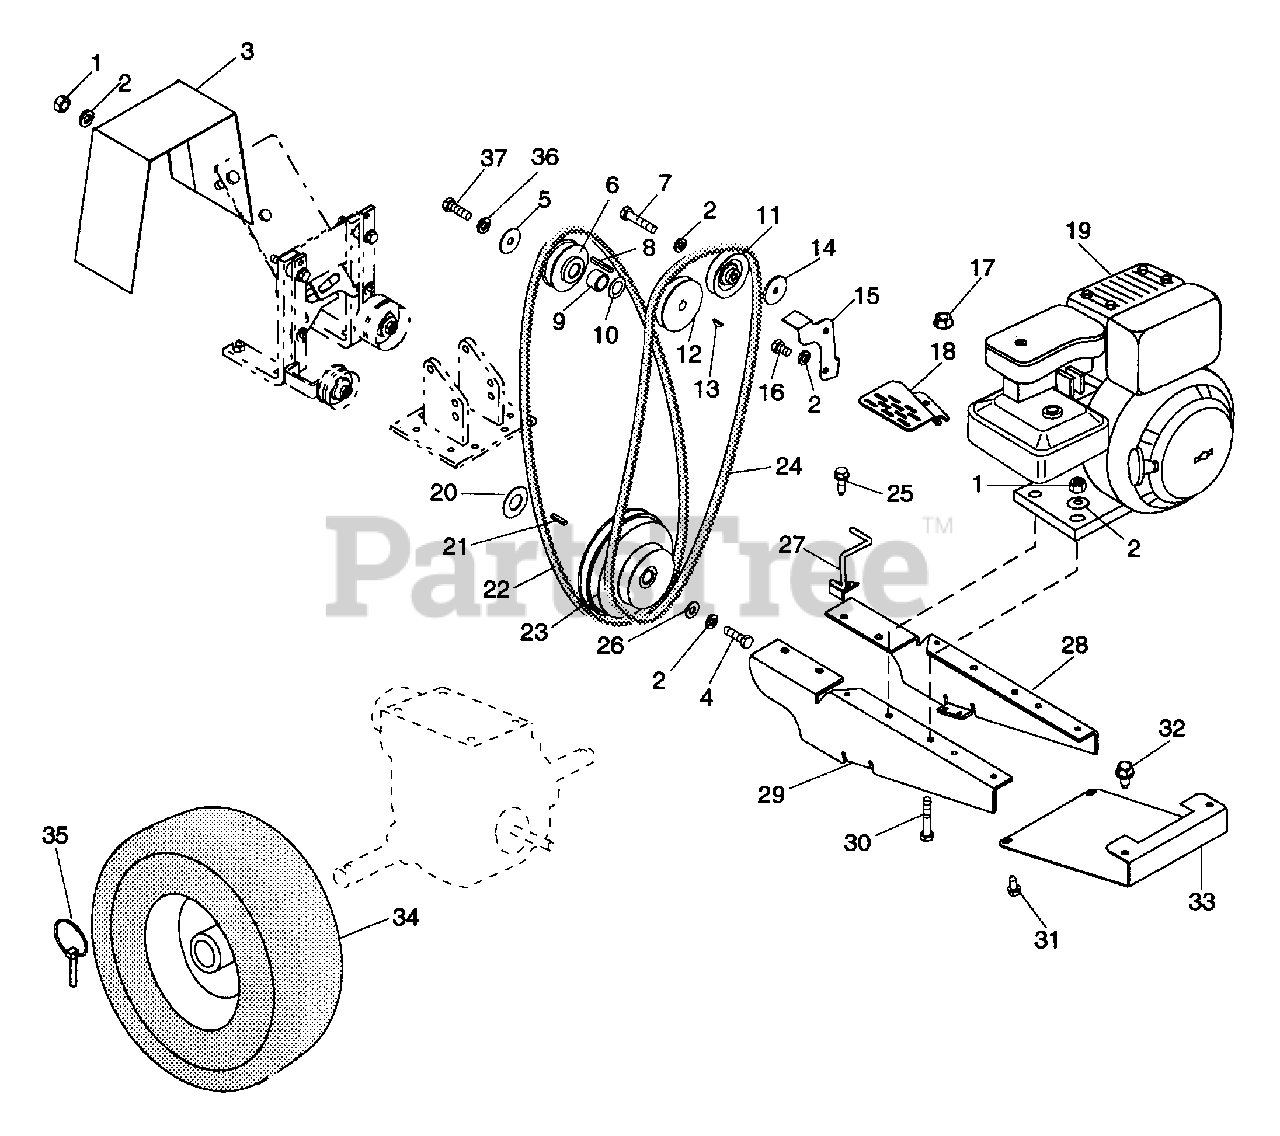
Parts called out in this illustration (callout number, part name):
1	NUT-HEX .312-18
2	WSHR-LK .312X.097 PL HVY
3	BELT GUARD W/DECALS
4	BLT-HEX .31-24X1.00 PL GR5
5	WSHR-FL-STL .344X1.125X.063PL
5	WSHR-FL-STL.406X.812X.065PL
6	SHEAVE, FORWARD
7	BLT-HEX .31-24X1.50 PL GR5
8	KEY-SQ .188X1.5X.187 SAE 8630
9	SPACER .765X.875X.750
9	SPACER .765X.875X.870
10	WSHR-HDND-THRST .758X1.23X.031
11	IDLER-V 2.625X.312
12	SHEAVE REVERSE
12	SHEAVE - REVERSE TEC 6HP
13	KEY-WDRF .125X.625X.250 SAE5
14	WSHR-FL-STL .312X1.62X.13
15	BELT FINGER
16	BLT-HEX .31-24X.50 GR5
17	NUT-FLG. .312-18 PL
18	MUFFLER SHIELD
18	MUFFLER GUARD
19	5 HP BRIGGS ENG 135292-0180-01
19	ENGINE, 4HP TILLER TEC.
19	ENGINE, 6HP TILLER TEC
20	WSHR-FL-STL .699X1.375X.059
21	KEY-SQ .188X1.0X.188 SAE 8630
22	V-BELT, 4L-WRAPPED
23	SHEAVE - TRANSMISSION
24	V-BELT, 3L-WRAPPED
24	BELT,3L WRAPPED
25	SCR-TAP .250-20X.75 HWH PL TR
26	WSHR-FL-STL .380X.875X.179 PL
27	BELT FINGER WELDMENT
28	L H ENGINE MTG BRKT
29	R H ENGINE MTG BRKT
30	BLT-HEX .31-18X1.75 GR5
31	SCR-TAP .250-20X.50 HXSLHDPL
32	SCR-TAP .312-18X.50 HWH PL TR
33	COVER, ENGINE BRKT
34	T/WHL ASSY RH
34	T/WHL ASSY LH
34	RIM-ASSY 1.75X3.13 SEE L-2080
34	TIRE
34	T/WHL ASSY LH 4.10-6 SL
34	T/WHL ASSY RH 4.10-6 SL
34	TIRE - 4.10-6 SUPER LUG
34	WHL-COMP 3.5 X 6
35	PIN-LOK .31X2.00
35	CLIP PIN 1/4-2.00
36	WSHR-LK .312X.097 PL HVY
36	WSHR-LK .375X.115 HVY PL
37	BLT-HEX .38-24X.75 GR5
37	BLT-HEX .31-24X1.00 PL GR5
